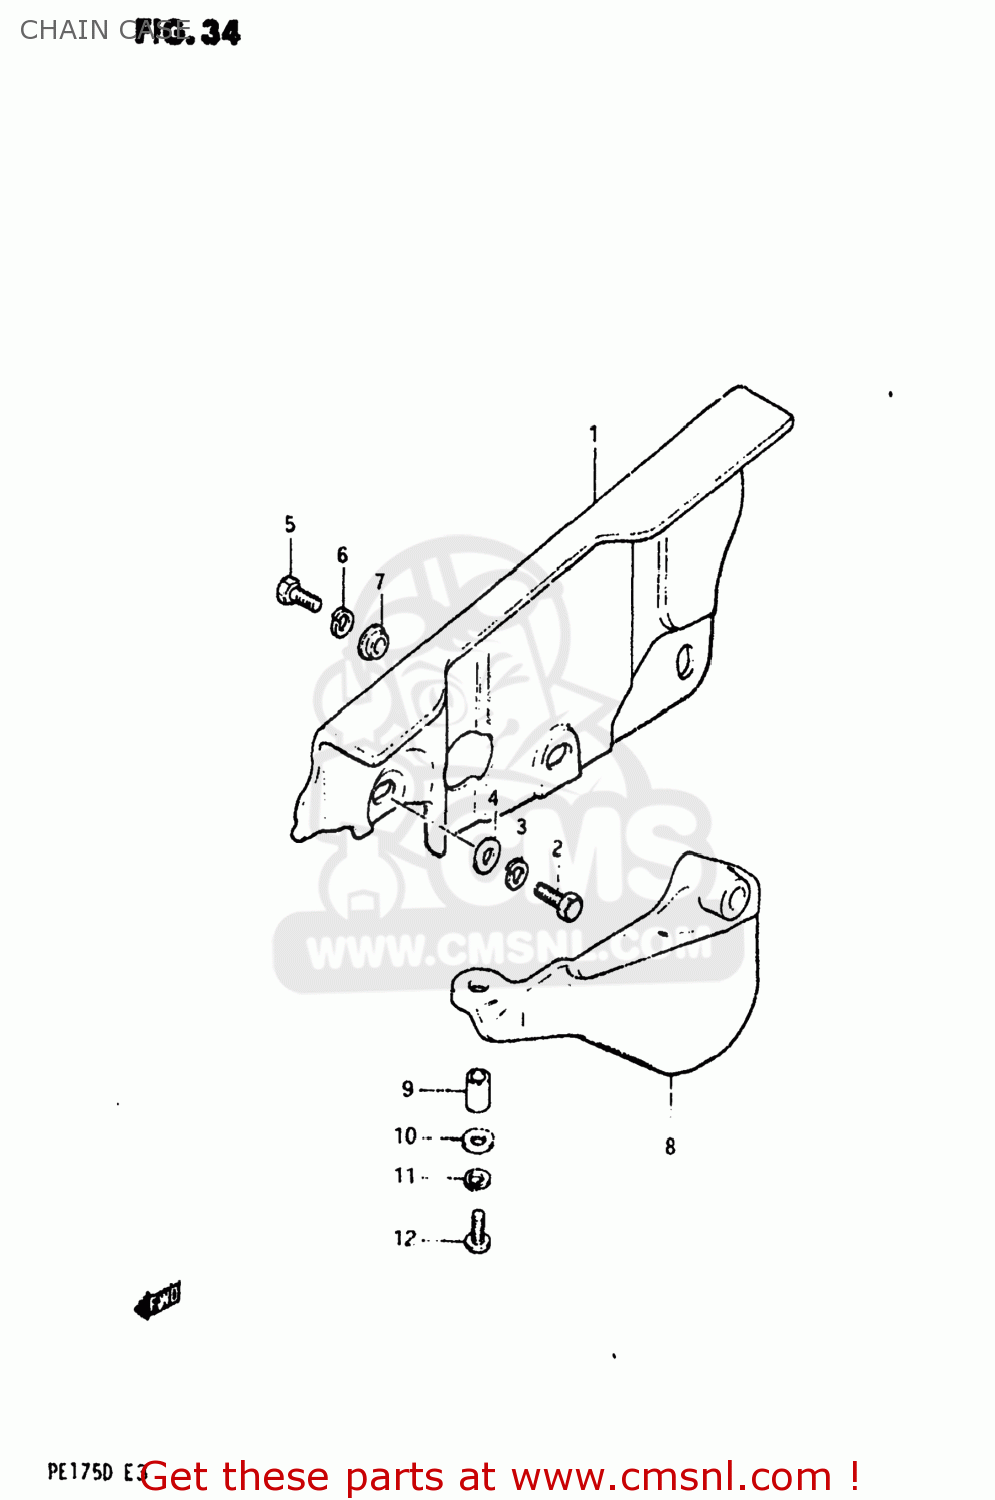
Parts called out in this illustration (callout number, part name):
1	CASE,CHAIN
2	BOLT, UPPER
3	LOCK WASHER
4	WASHER(6.5X18X1)
5	BOLT
6	LOCK WASHER
7	WASHER
8	RUBBER,CHAIN CASE,LOWER
9	SPACER (6.1X8X5.2)
10	WASHER(6.5X18X1)
11	LOCK WASHER
12	SCREW 6X12
